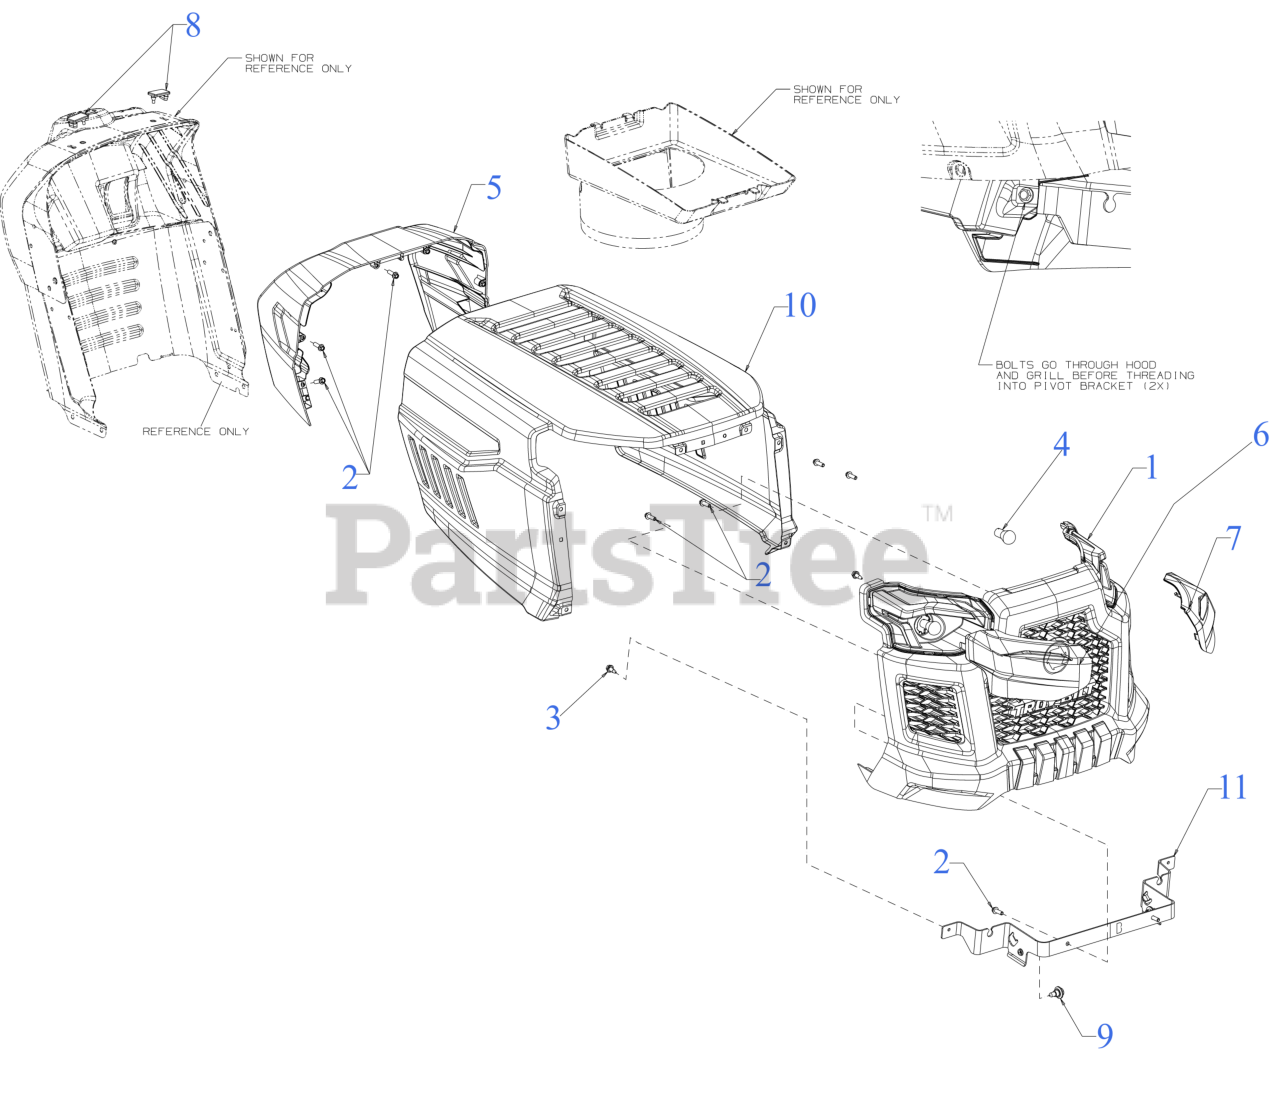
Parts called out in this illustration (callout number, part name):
1	FRONT GRILLE
2	SCREW 1/4 x .750
3	SCREW 1/4-20X.625
4	MINIATURE LAMP-12V #1156
5	HOOD COLLAR
6	HEADLIGHT LENS (RH)
7	HEADLIGHT LENS (LH)
8	HOOD BUMPER PAD
9	SHOULDER SCREW .43X.29X5/16-18 TT
10	HOOD
